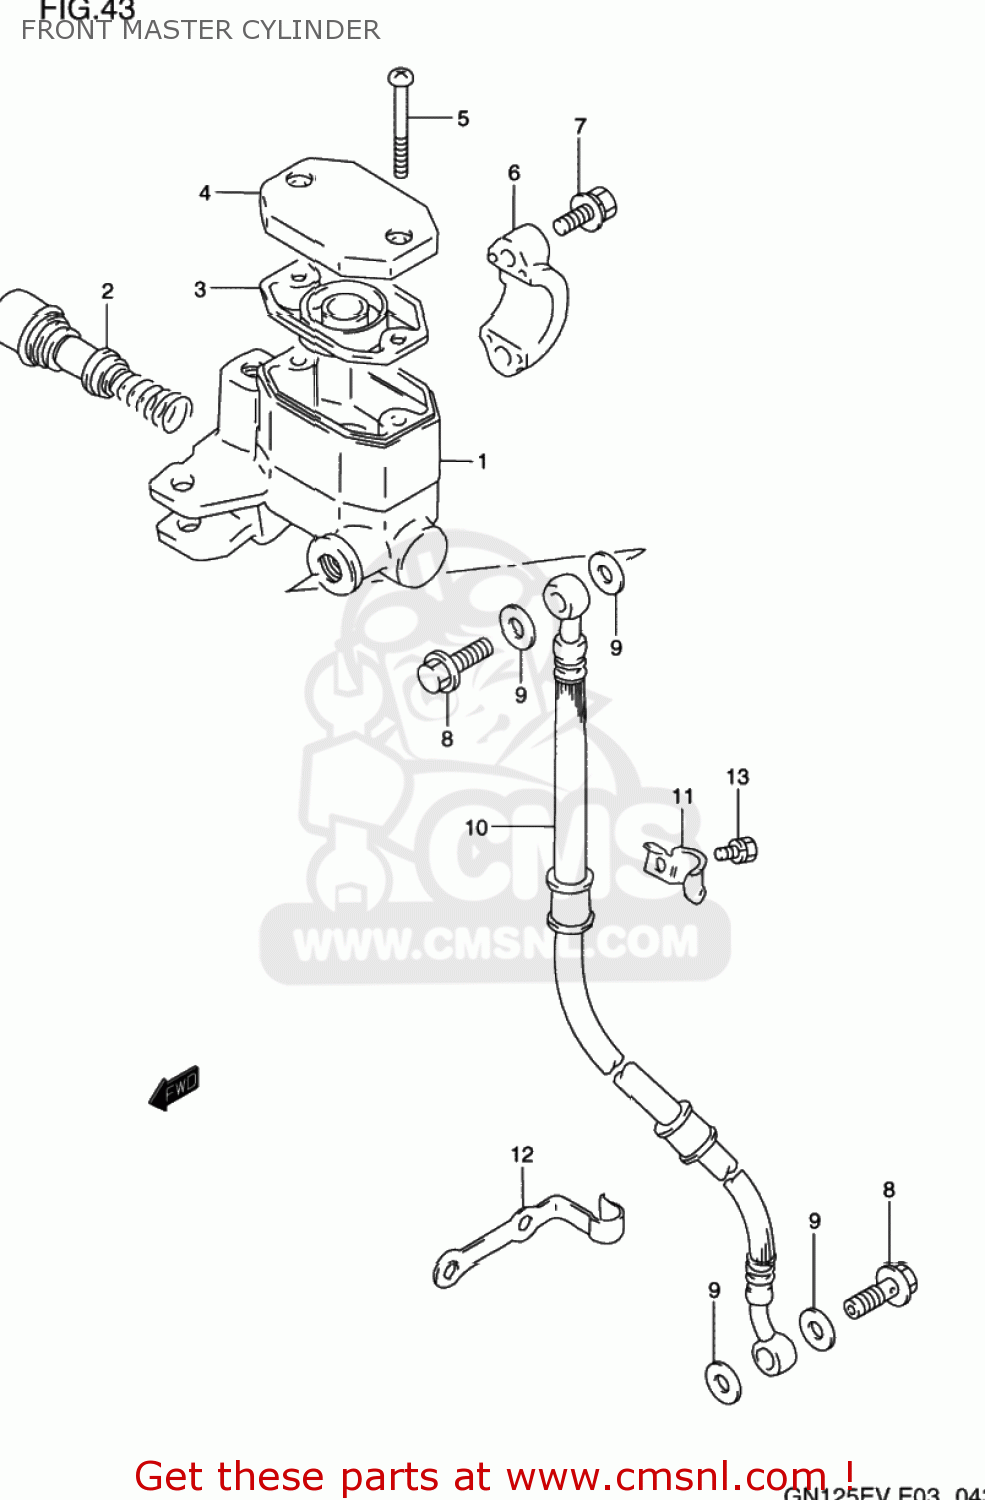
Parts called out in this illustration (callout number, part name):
1	CYLINDER ASSY,FR MASTER
2	PISTON/CUP SET
3	DIAPHRAGM
4	CAP
5	SCREW
6	HOLDER
7	BOLT(6X25)
8	BOLT UNION
9	WASHER(10X15X1.5)
10	HOSE,FR BRAKE
11	CLAMP,BRAKE HOSE
12	CLAMP,BRAKE HOSE
13	BOLT
